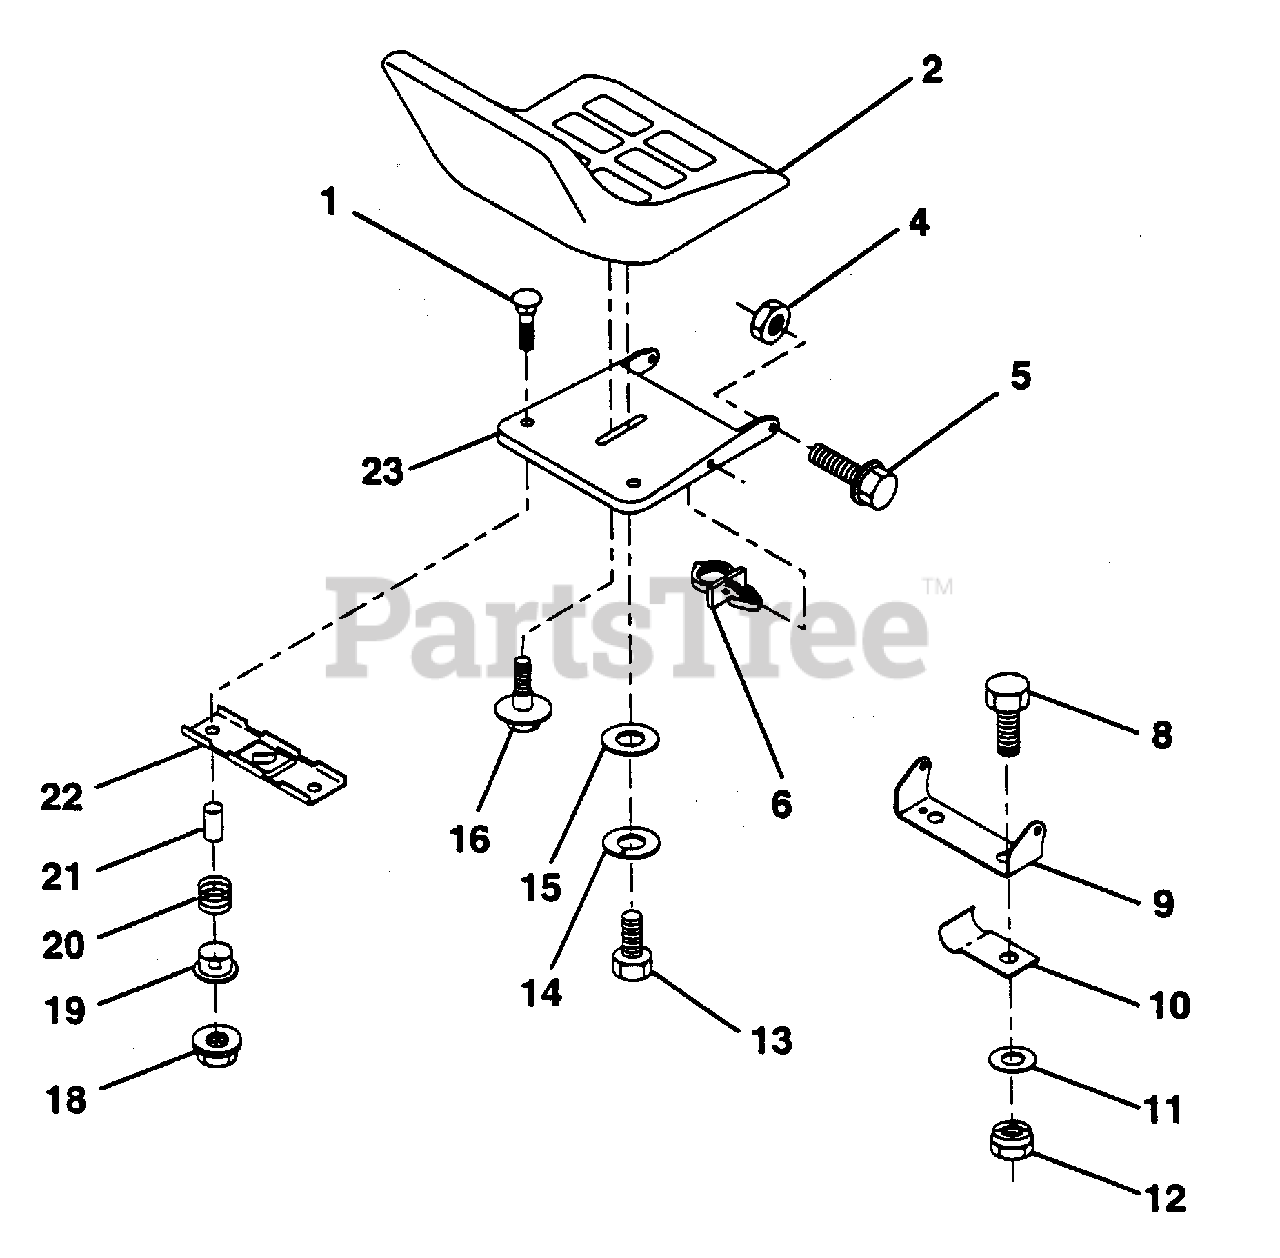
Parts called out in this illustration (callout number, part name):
1	Bolt, Carriage 1/4-20 x 1-3/8
2	Seat
4	Locknut, Hex w/Ins 5/16-18
5	Bolt, Shoulder 5/16-18 UNC
6	Clip, Insulated
8	Bolt, Fin Hex 3/8-16 UNC x 1
9	Bracket, Pivot Seat
10	Clip, Insulated
11	Washer 12/32 x 2 x 10 Ga.
12	Nut, Lock Hex w/Wsh 3/8-16
13	Bolt Hex 1/2-13 x 7/8
14	Washer Lock Hvy. Hlicl Spring 1/2
15	Washer, 17/32 x 1-3/16 x 12 Ga.
16	Bolt, Shoulder
18	Nut, Hex Large Flange Lock
19	Bushing, Snap
20	Spring, Compression
21	Spacer, Split 28 Id. x .88 Lg.
22	Bracket, Switch, Mounting
23	Pan, Seat
